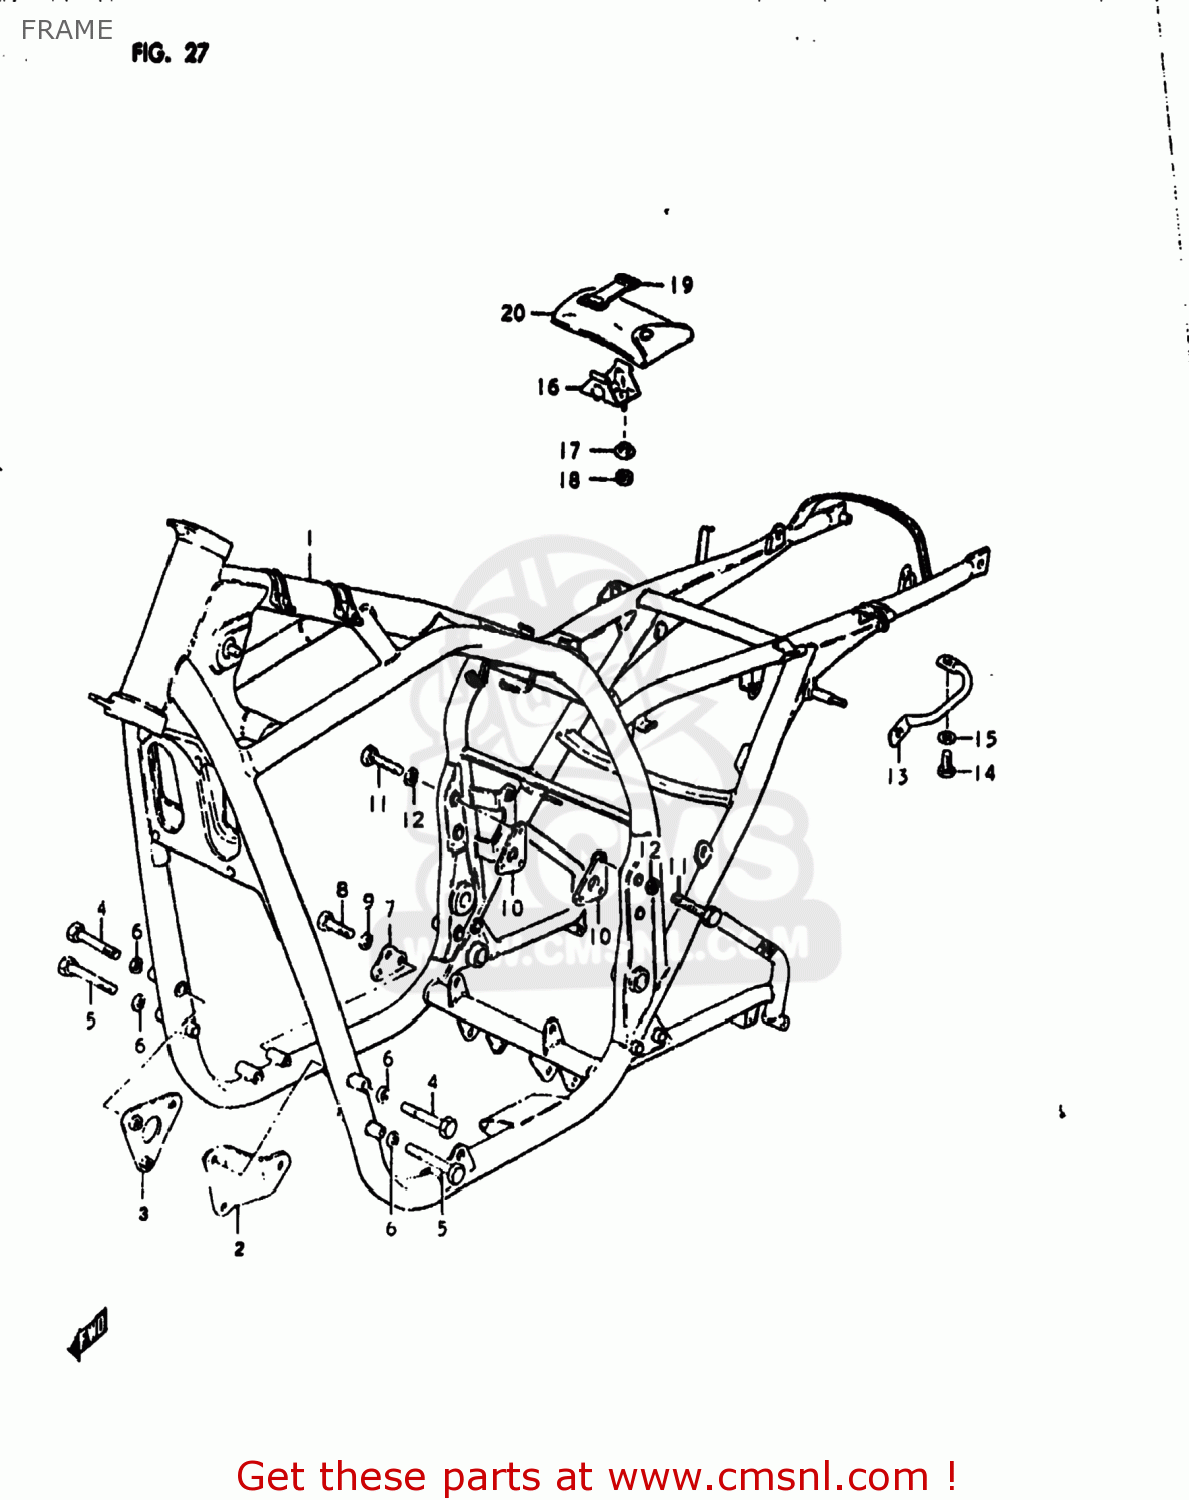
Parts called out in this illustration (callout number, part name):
1	FRAME
2	PLATE,ENGINE MOUNTING
3	PLATE,ENGINE MOUNTING
4	BOLT
5	BOLT
6	LOCK WASHER
7	PLATE,ENGINE MOUNTING
8	BOLT
9	LOCK WASHER
10	PLATE,ENGINE MOUNTING
11	BOLT
12	LOCK WASHER
13	GRIP,FRAME
14	BOLT
15	WASHER
16	HOLDER,TOOL
17	WASHER
18	NUT
19	BAND
20	TOOL SET
